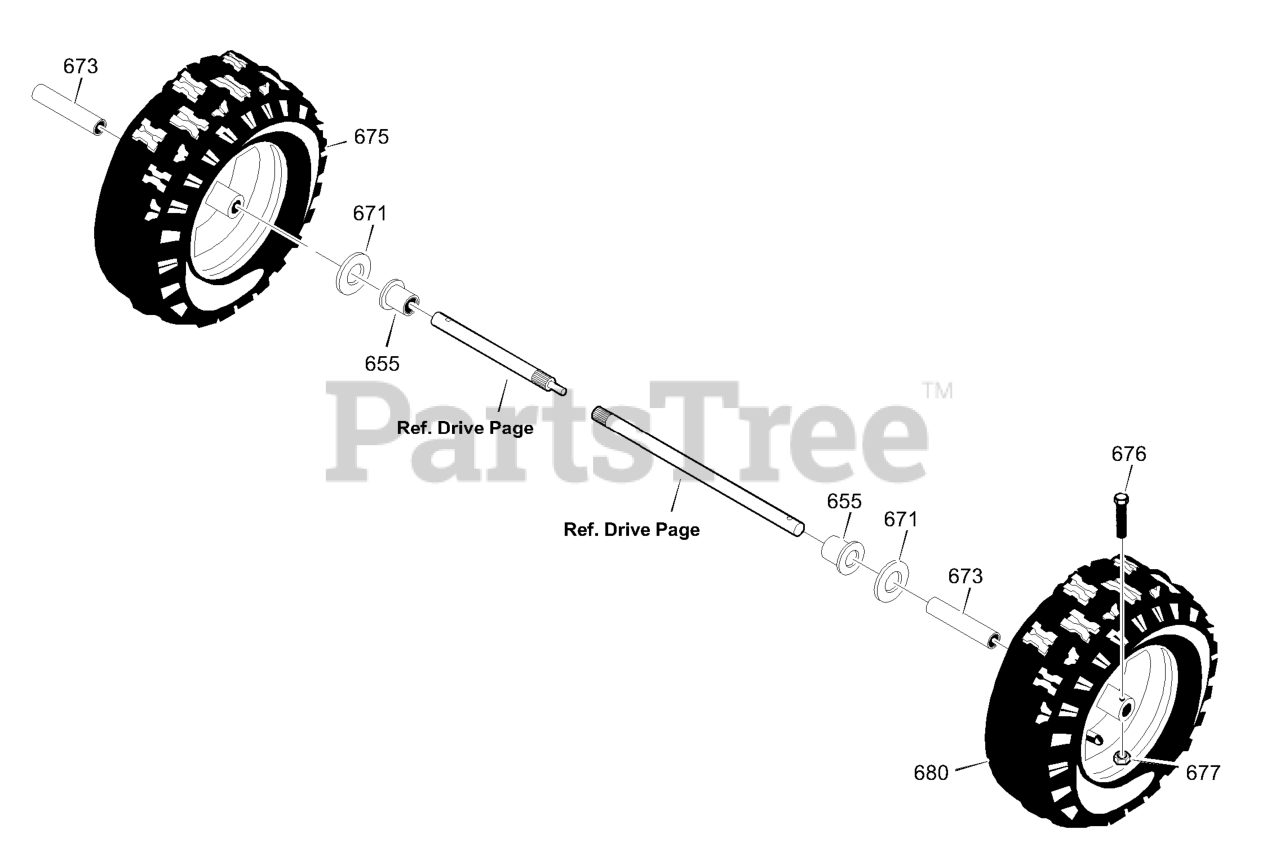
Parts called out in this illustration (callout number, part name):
655	BEARING, AXLE
671	FLATWASHER
673	BUSHING, WHEEL
675	TIRE & RIM, LEFT
676	SCREW, 1/4-20X1.75 HH
677	NUT, 1/4-20 HEX NYLOCK
680	TIRE & RIM, RIGHT
